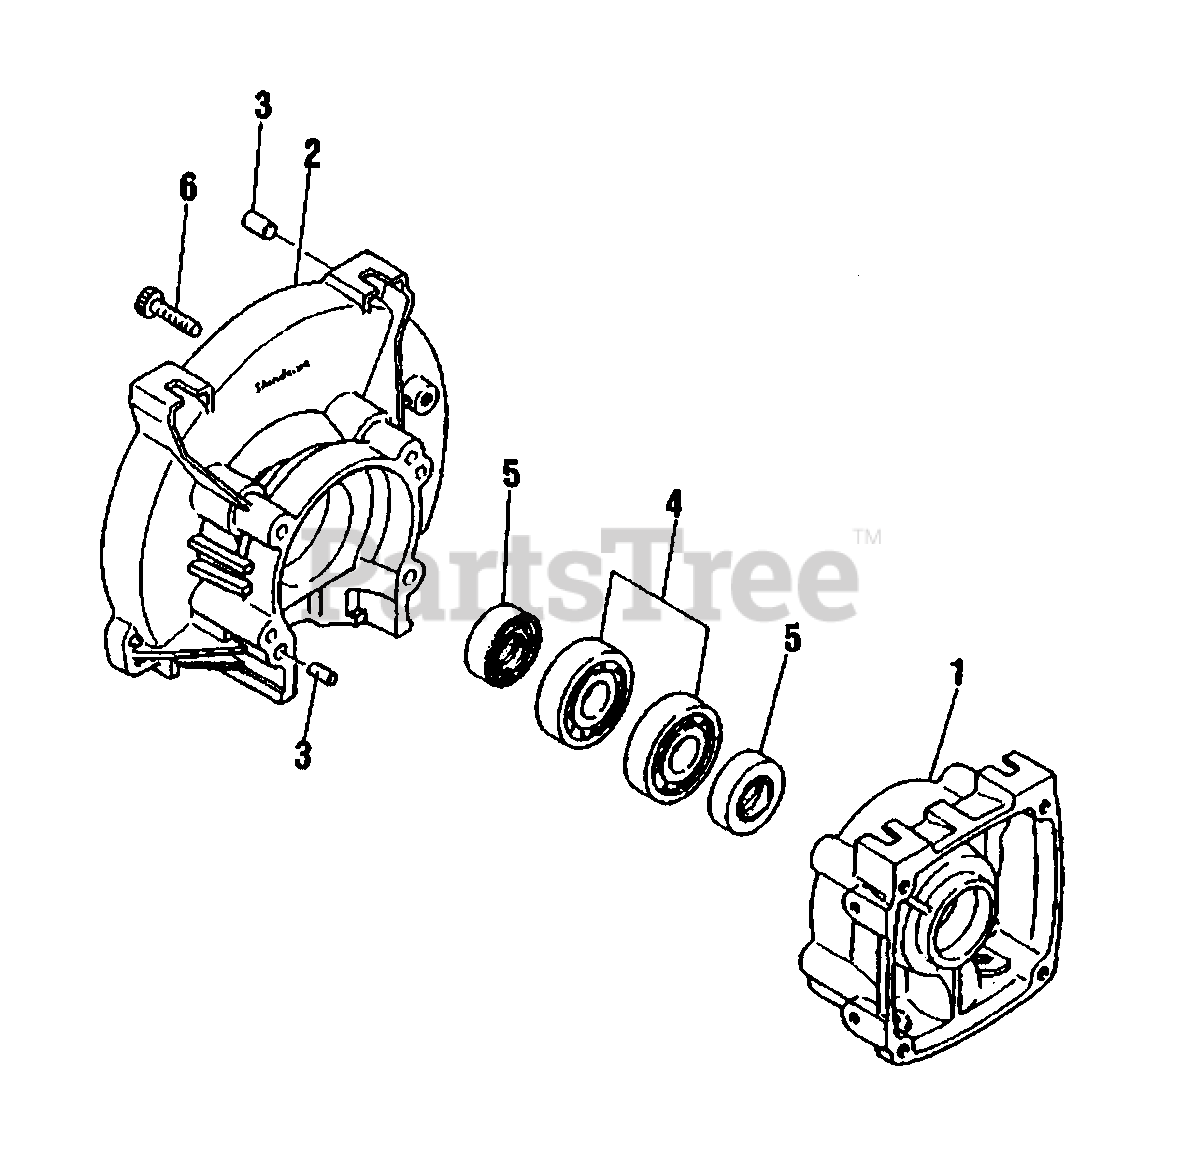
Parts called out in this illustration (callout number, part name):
1	CRANKCASE - REAR
2	CRANKCASE - FRONT
3	PIN - LOCATING
4	BEARING, BALL - 6202
5	SEAL, OIL
6	SCREW - 5X30
